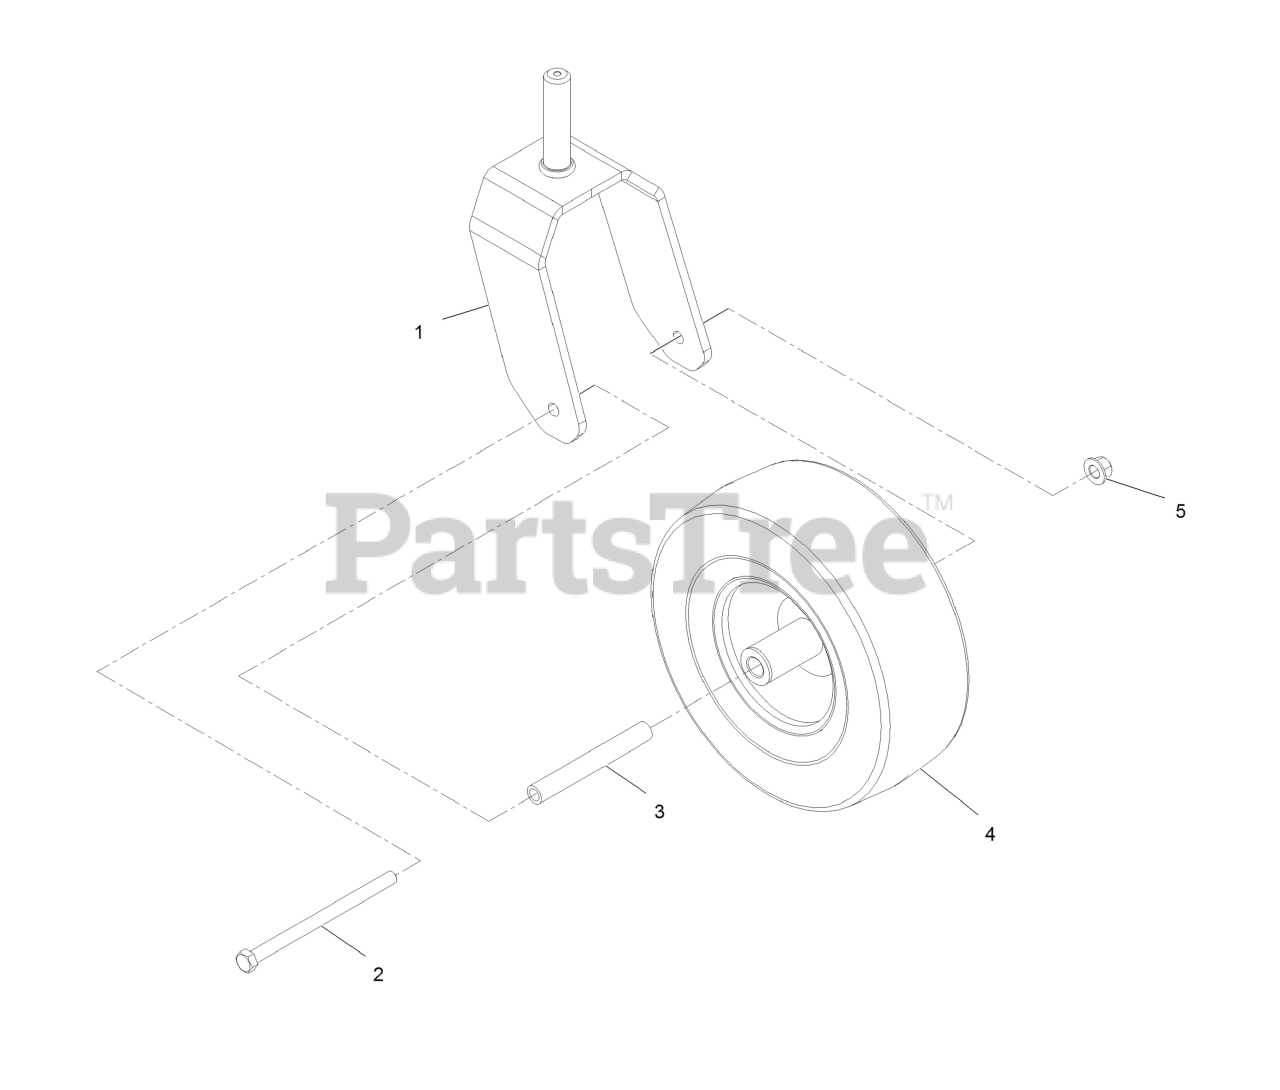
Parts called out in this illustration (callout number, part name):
1	CASTER-FORK
2	SCREW-HH
3	SPANNER
4	TIRE AND WHEEL ASM
5	Nut-Lock 1/2-13
